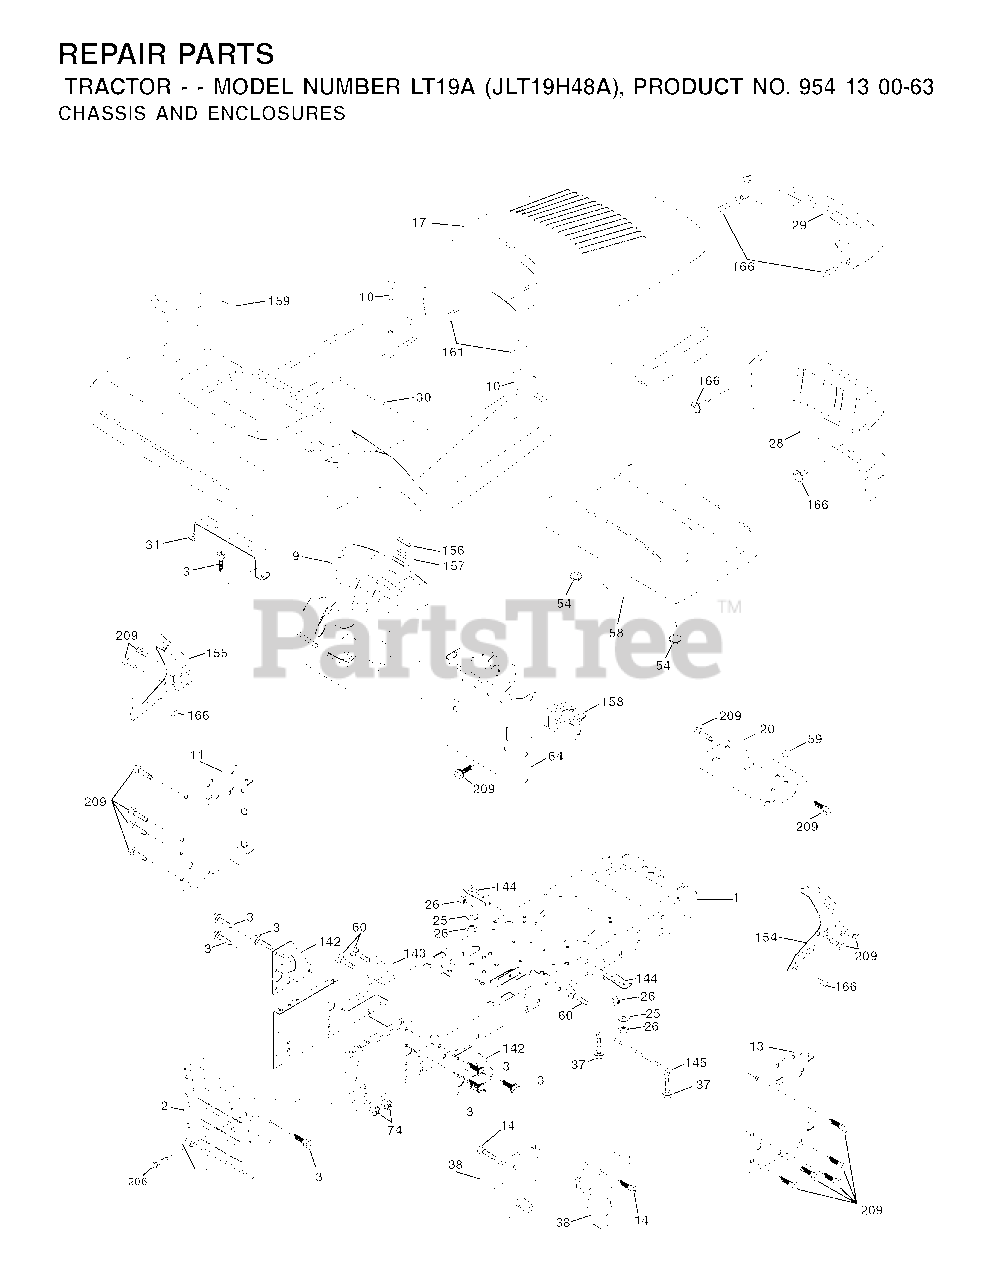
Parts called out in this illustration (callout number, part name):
1	CHASSIS STAMPING
2	DRAWBAR, 12GA
3	SCREW 3/8-16X3/4
10	BOLT D
25	WASHER
26	NUT
38	BRACKET.ASM.PIVOT.MOWER.REAR
58	DUCT HOOD
59	BUSHING 1.375 OD
64	DASH LOWER
74	LOCKNUT
142	PLATE REINFORCEMENT
143	BRACKET, SWAY BAR
144	BRKT, FOOT REST
145	ROD PIVOT CHASSIS/HOOD
161	EXTRUSION BUMPER
166	SCREW
206	SHOULDER BOLT 5/16-18TT
209	SCREW, 3/8-16X3/4
